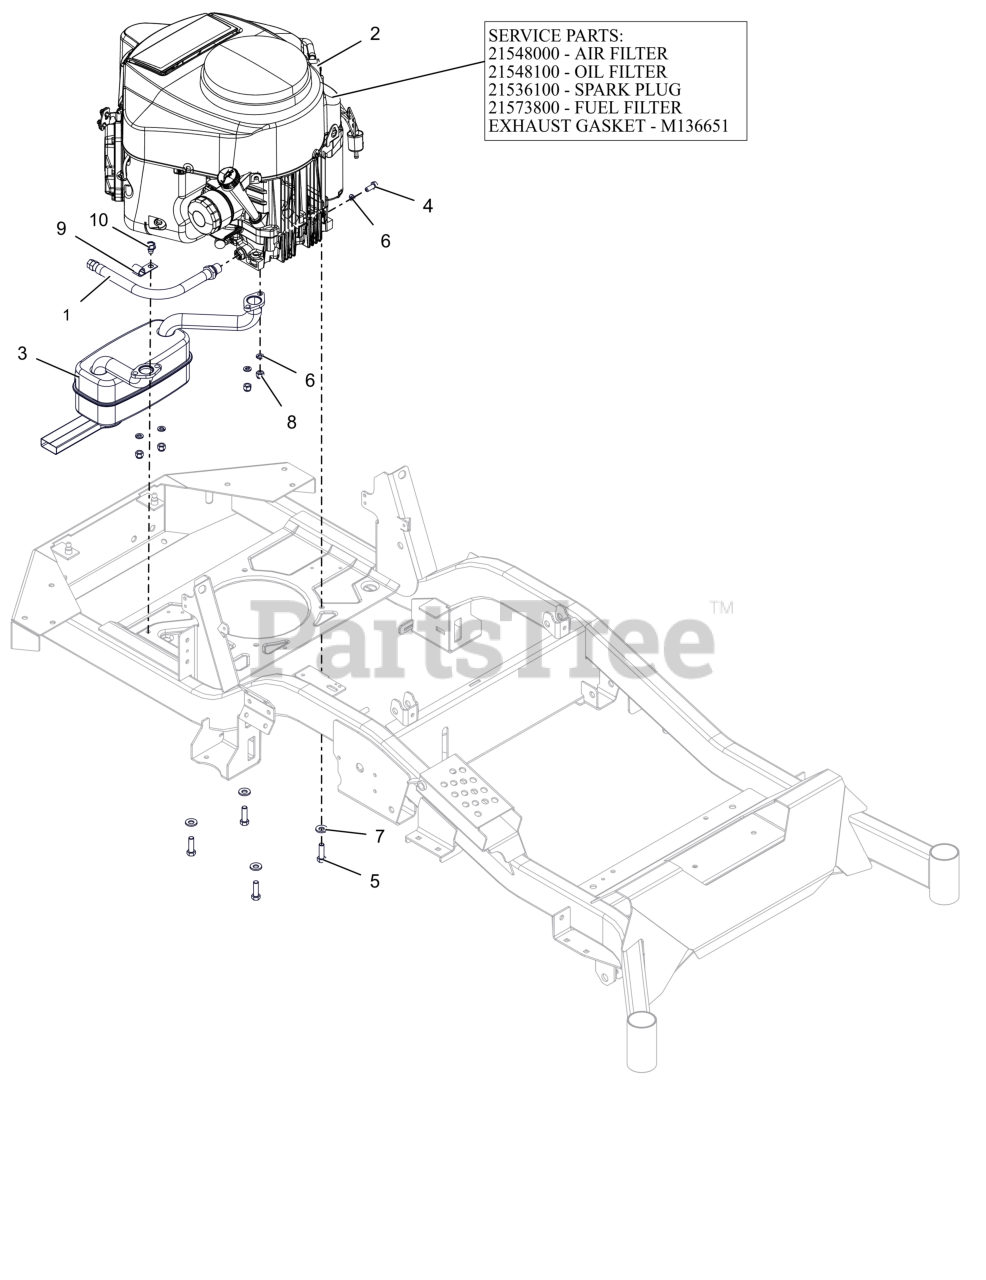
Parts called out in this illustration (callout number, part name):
1	HOSE, OIL DRAIN
2	AIR FILTER, KAWASAKI FR
2	OIL FILTER, KAWASAKI FR
2	PLUG, SPARK
2	FUEL FILTER-KAWASAKI FR
2	GASKET, MUFFLER #
3	MUFFLER, KAWASAKI
4	BLT, HEX M8-1.25X20 G8.8 ZCC
5	BLT, HEX .38-16X1.25 G5 ZCC NT
6	WSHR,LK-REG .312X.078 ZCC
7	WASHER, 3/8" SPRING DISC
8	NUT, LK-CTR-JAM M8-1.25 GR8.8 ZC120
9	J-CLAMP
10	SCR,TAP .375-16X.50 HWH TR ZCC
